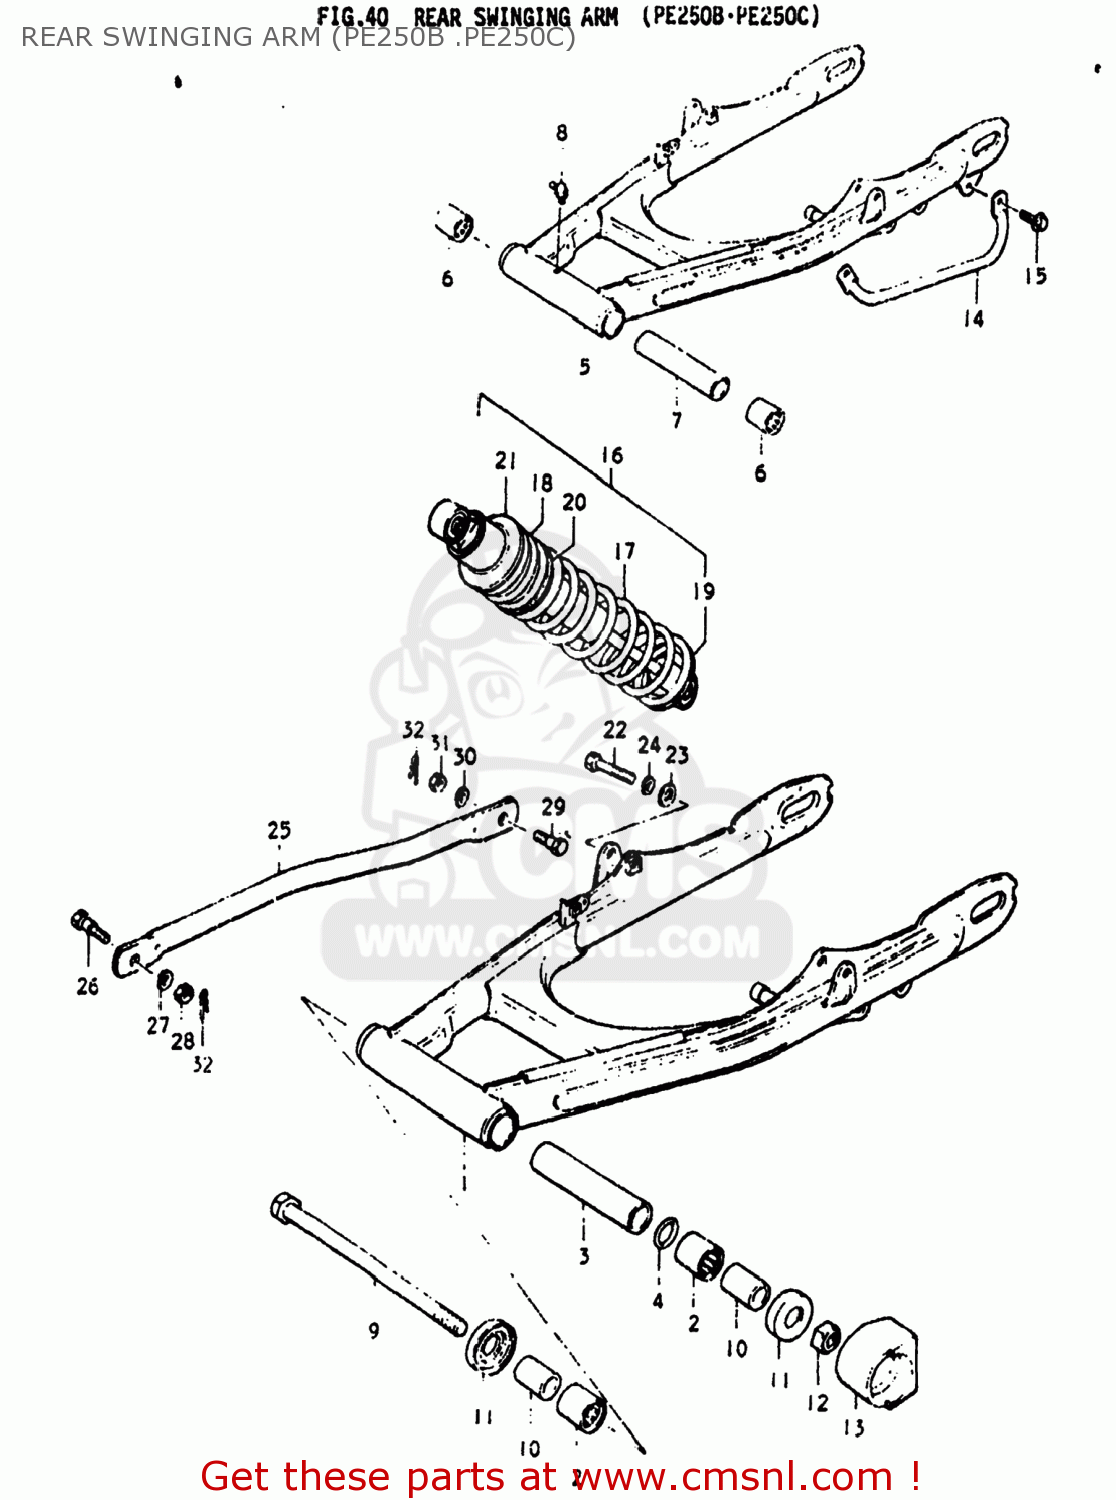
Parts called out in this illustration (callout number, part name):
1	SWING ARM ASSEMBLY,REAR
2	BEARING(20X28X25)
3	SPACER,REAR SWING ARM
4	O RING(D:1.9,ID:18.8)
5	SWING ARM ASSEMBLY,REAR
6	BEARING(20X28X25)
7	SPACER,REAR SWING ARM
8	NIPPLE,GREASE
9	SHAFT,REAR SWING ARM
10	SPACER(14X20X30)
11	THRUST BEARING IKO
12	NUT 14MM
13	BUFFER,CHAIN TOUCH DEFENSE
14	GUARD
15	BOLT 8X12
16	ABSORBER ASSEMBLY,REAR SHOCK
17	SPRING
18	SPRING
20	SPRING
21	GUIDE,SPRING
22	BOLT 10X40
23	WASHER
24	LOCK WASHER
25	TORQUE LINK,REAR
26	BOLT(8X22.5)
27	LOCK WASHER
28	NUT
29	BOLT(10X31)
30	LOCK WASHER
31	NUT
32	CLIP
